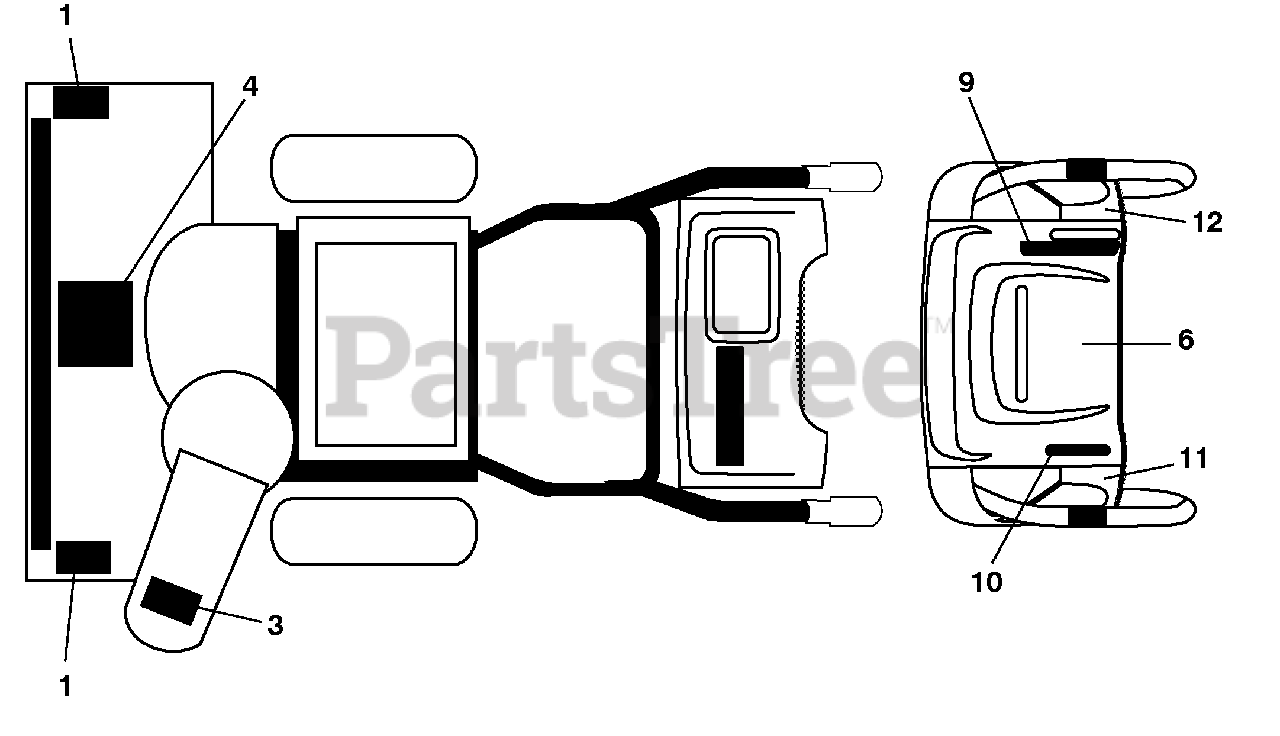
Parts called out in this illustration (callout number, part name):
1	DECAL, DANGER
3	DECAL, DANGER, DEFLECTOR
4	DECAL, DANGER
6	DECAL, INSTRUC.
9	DECAL, REMOTE DEFLEC. CONTROL
10	DECAL, REMOTE DEFECTOR CONTROL
11	DECAL, TRIGGER LH
12	DECAL, TRIGGER RH
12	OWNER'S MANUAL, ENGLISH
12	OWNER'S MANUAL, FRENCH
